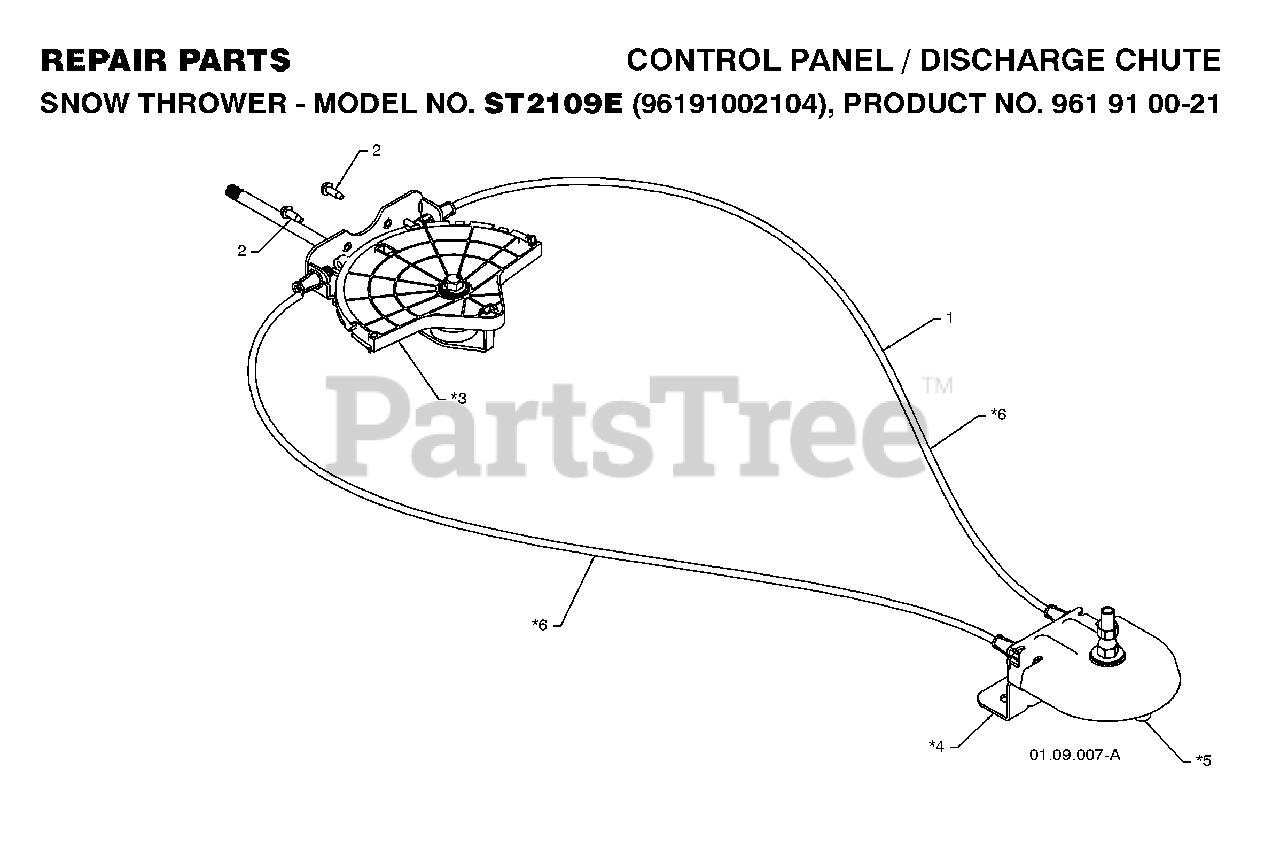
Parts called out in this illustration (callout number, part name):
1	LEVER/CABLE.ASM.ROTATOR
2	SCREW #10-24 X 5/8
3	CHUTE.ROT.HEAD.SERVICE
4	PIVOT.BRACKET
5	SNOW.PIVOT.PULLY
6	CABLE.ASSEMBLY
